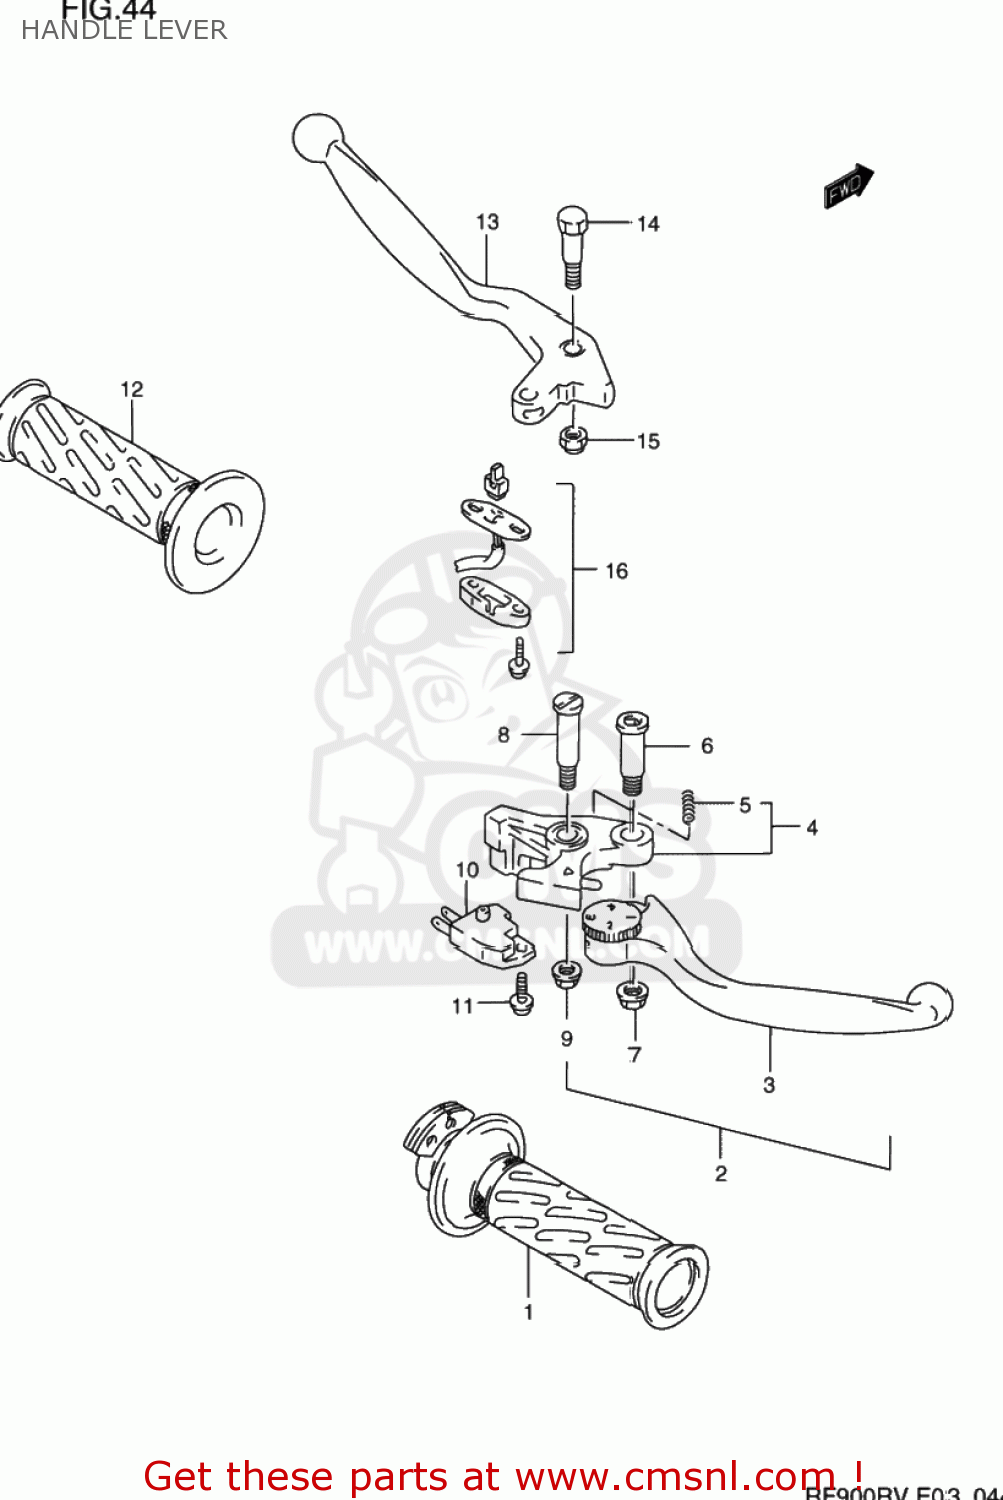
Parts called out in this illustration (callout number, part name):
1	GRIP,THROTTLE
2	LEVER ASSEMBLY,BRAKE
3	LEVER,ADJUST
4	KNOCKER
5	SPRING
6	BOLT,LEVER
7	NUT
8	BOLT,LEVER PIVOT
9	NUT
10	SWITCH ASSEMBLY,STOP
11	SCREW
12	GRIP,LEFT
13	LEVER,CLUTCH (SILVER)
14	BOLT,LEVER
15	NUT
16	SWITCH ASSY,CLUTCH
